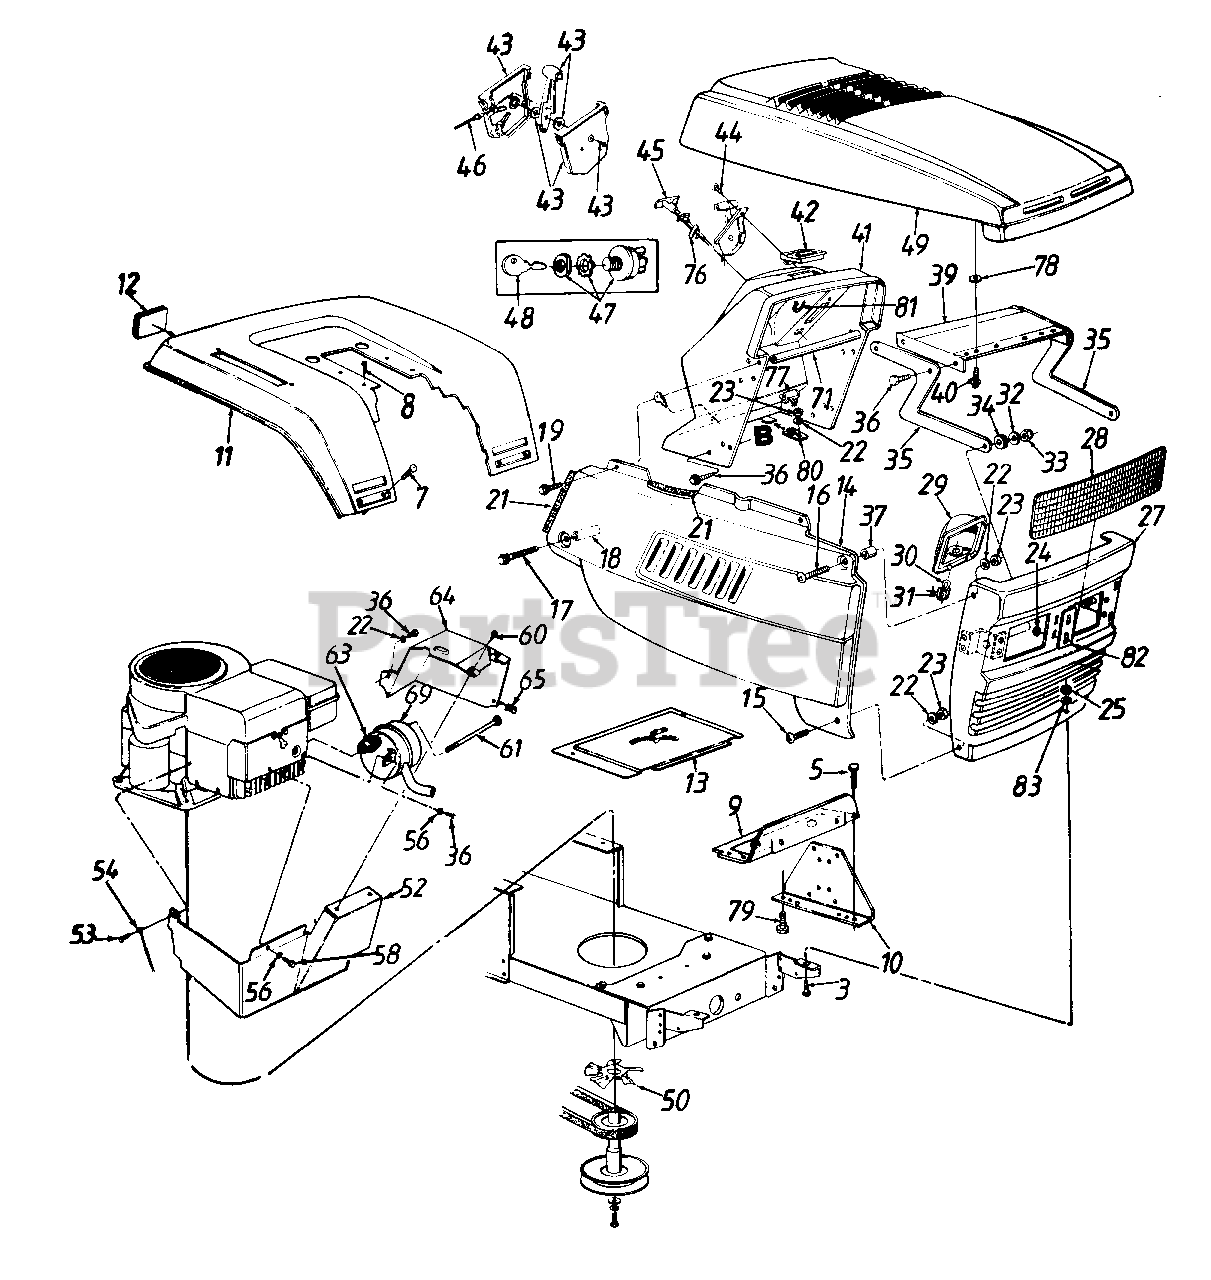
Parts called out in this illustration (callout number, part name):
3	Hex Bolt 5/16-18 x .75" Lg.
5	Hex Wash. Hd. Scr. 5/16" x .5" Lg.
7	Carriage Bolt 1/4-20 x .5" Lg.
8	Hex Wash. Hd. Tap Scr. 5/16 x .75" Lg.
16	Truss Mach. Scr. 1/4-20 x 1.0" Lg.
17	Hex Wash. TT-Tap Scr. 1/4-20 x 1.75" Lg.
18	Spacer .26" I.D. x 1.32"
19	Hex Rolling Tap Scr. 1/4-20 x .75" Lg.
21	Trim Strip - 18" Lg.
22	L-Wash. 1/4" I.D.
23	Hex Nut 1/4-20 Thd.
24	Speed Nut 5/16" Thd.
25	Hex Nut 5/16-18 Thd.
26	Fl-Wash. .344" I.D. x 1" O.D.
29	Headlamp Housing
30	Headlamp
31	Twist Lock Lamp Socket
32	Bell-Wash. .345" I.D. x .88"
33	Hex L-Nut 5/16-18 Thd.
34	Rubber Washer
37	Spacer .262" I.D. x .31"
41	Dash
42	Ammeter
43	Throttle Control Box Ass'y.
44	Mach. Scr. #10 x .44" Lg.
45	Choke Control 23" Lg.
46	Throttle Control Wire 18.5" Lg.
47	Ignition Switch
48	Ignition Key
49	Hood - Red
52	Muffler Heat Shield-Front
53	Truss Mach. Scr. 5/16-18 x .75" Lg.
54	Ground Wire
56	Spr. Wash. 1/4" I.D.
58	Hex Bolt 1/4-20 x 3/8" Lg.
60	Hex B-Tap Scr. #10 x .38" Lg.
61	Shoulder Bolt
63	Exhaust Gasket
64	Muffler Heat Shield - L.H.
65	Speed Nut #10-24 Thd.
69	Muffler
71	Grille Support Tube
73	External L-Wash. 5/16" I.D.
76	Choke Retainer
77	Light Switch
78	Fl-Wash. .406" I.D. x .812" O.D.
79	Hex Bolt 1/4-20 x .62" Lg.
80	Dash Fastening Tab
81	Cable Tie
82	Chrome Label
